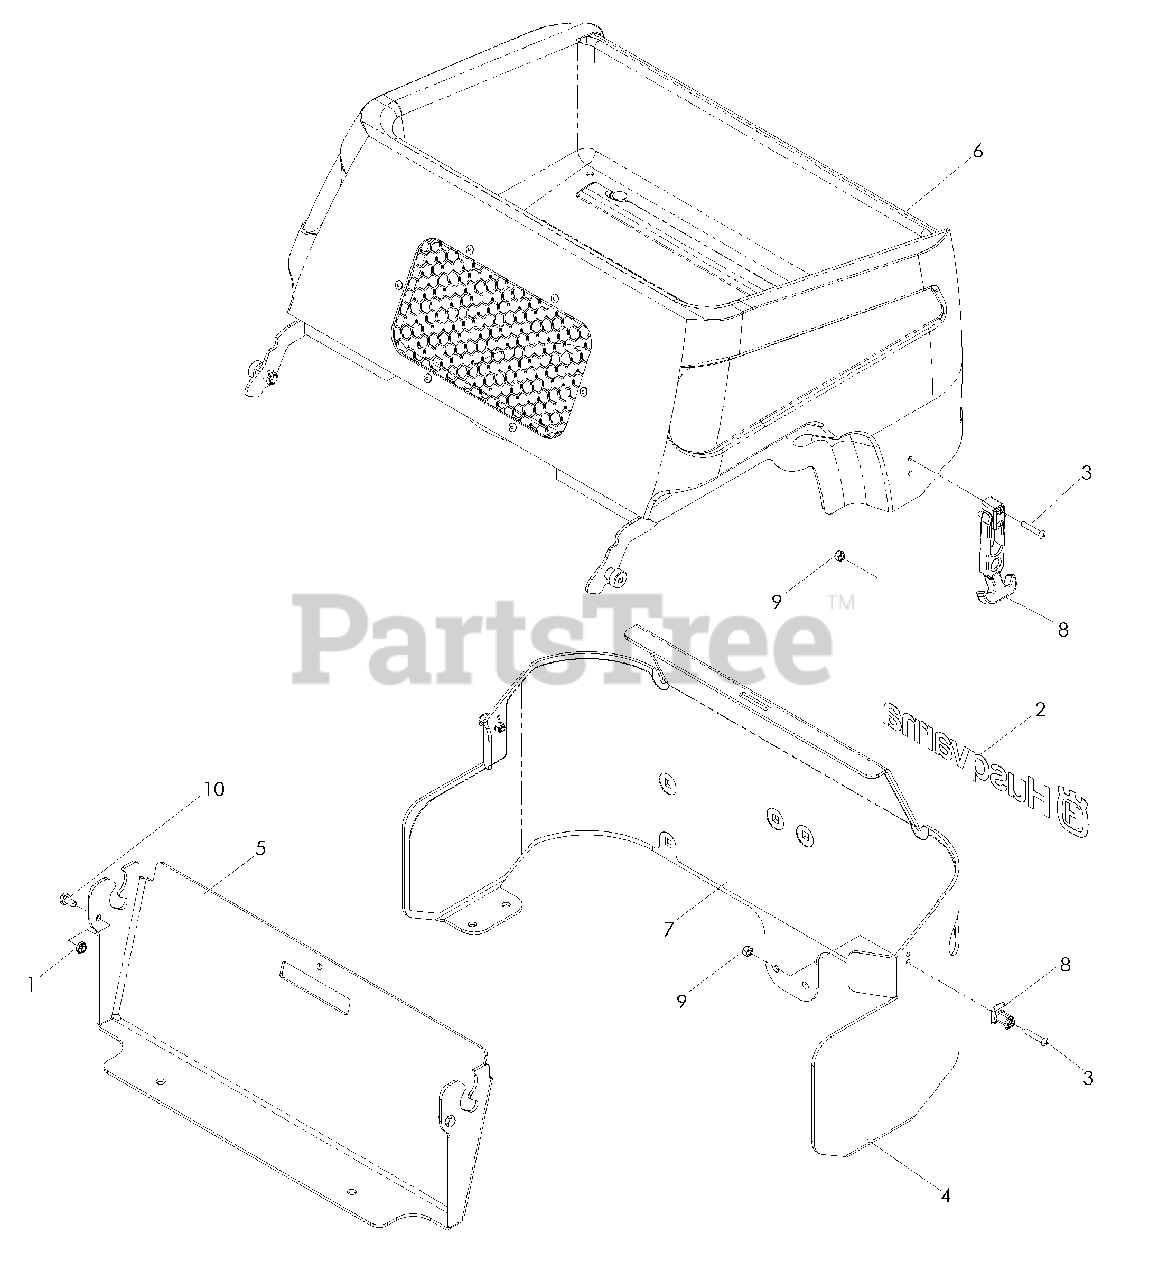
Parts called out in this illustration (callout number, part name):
1	NUT, 1/4-20, THIN, NYLOC
2	DECAL, HUSQVARNA
3	SCREW, #10-24 x 1 1/8
4	REAR GUARD
5	FRONT SUPPORT
6	HOOD ASSEMBLY
7	BARRIER, HEAT
8	DRAW LATCH
9	NUT, #10-24, NYLOC
10	HCS, 1/4-20 x 1/2
